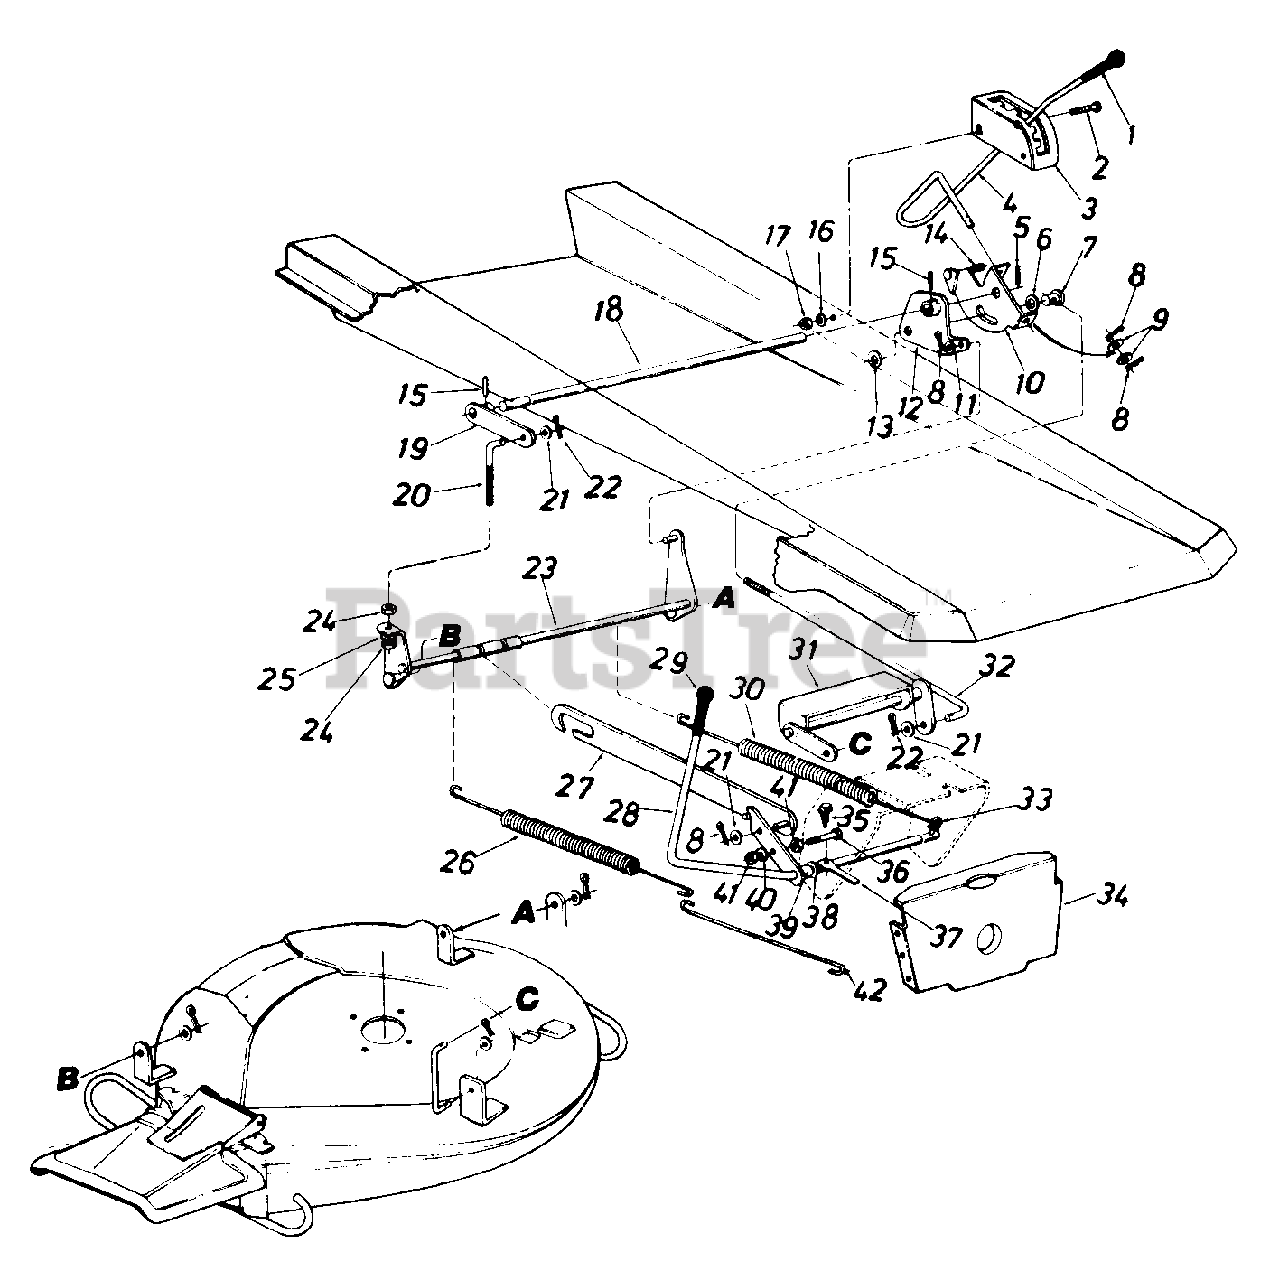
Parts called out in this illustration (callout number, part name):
2	Truss Mach. Scr. 5/16-18 x 75" Lg.
5	Spring Pin Spir. 3/16" Dia. x 1.50" Lg.
6	Fl-Wash. 885" I.D. x 87" O.D.
7	Adj. Ferrule Deck Lift Handle
8	Cotter Pin 1/8" Dia. x 1.00" Lg.
9	Fl-Wash. .531" I.D. x 930" O.D.
10	Deck Lift Handle Retainer Ass'y.
11	Fl-Wash. .385" I.D. x .87" O.D.
12	Deck Lift Brkt. Ass'y. L.H.
13	Fl-Wash. .635 I.D. x 1.04" O.D.
14	Compression Spring .50" Dia. x 1.0" Lg.
15	Spring Pin Spir. l/4" Dia. x 1.50" Lg.
16	L-Wash. 5/16" I.D.
17	Hex Nut 5/16-18 Thd.
18	Rear Hgt. Adj. Shaft
19	Deck Lift Brkt. Ass'y. R.H.
20	Deck Adj. Scr. 3/8-16 Thd.
21	Fl-Wash. 885" I.D. x 87" O.D.
22	Intern. Cotter Pin 1/2" Dia.
23	Deck Link Ass'y. Rear
24	Hex Nut 3/8-16 Thd.
25	L-Wash. 3/8" I.D.
26	Extension Spring .73" O.D. x 13.84" Lg.
27	Deck Drive Control Bracket
28	Blade Engagement Lever Ass'y.
30	Extension Spring .73" O.D. x 13.89" Lg.
31	Deck Lift Ass'y. Front
32	Deck Lift Connecting Rod
33	Clevis Pin Special .250" Dia.
34	Pivot Bar Bracket
35	Hex TT-Tap Scr. 1/4-20 X .75" Lg.
36	Hex Bolt 5/16-18 x 1.50" Lg. (Grade 5)
37	Switch Actuator
38	Fl-Wash. .531" I.D. x .930" O.D.
39	Spacer .511" I.D. x .70" O.D. x.38" Lg.
40	L-Wash. 6/16" I.D.
41	Hex Nut 5/16-18 Thd.
42	Spring Hook
